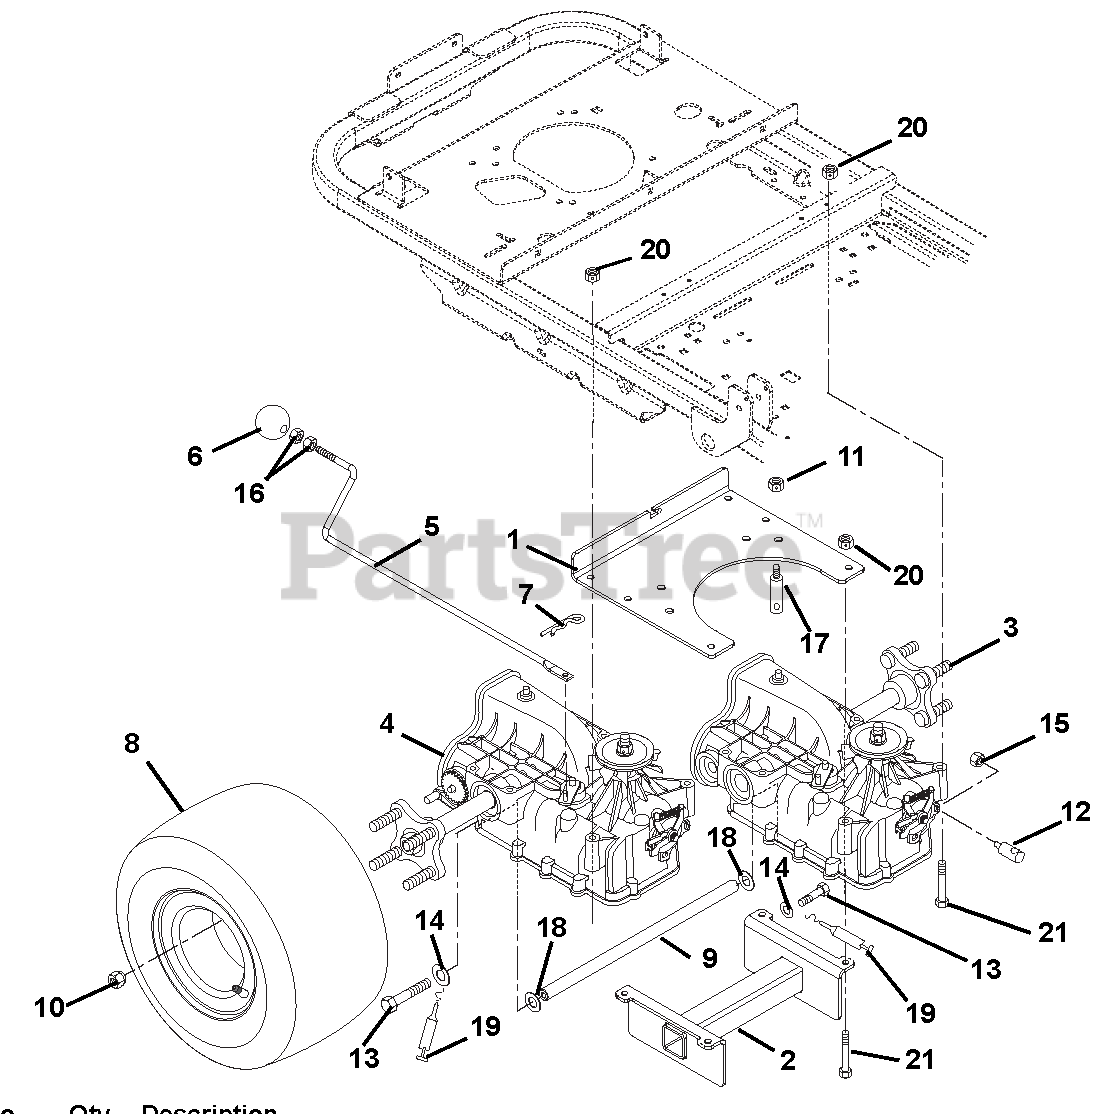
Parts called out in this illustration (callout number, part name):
1	BKT-TRANS AXLE SUPPORT
2	WLDMT-TRANS AXLE BRACE
3	IZT-LH (BIDIRECTIONAL RTN)
3	KIT, LH-BRAKE ARM IZT
4	IZT-RH (BIDIRECTIONAL RTN)
4	KIT,RH-BRAKE ARM IZT
5	ROD-DUMP IZT
6	KNOB, BALL 5/16-18 X 1.5
7	PIN-HAIR INT .08X.18X1.18 YWZC
8	ASSY-TIRE 9.5X18-2PLY
8	ASSY-TIRE 8.5X18 2PLY
9	ROD-AXLE BRACE
10	NUT-LUG .50-20 YWZC
11	@NUT-LK-NYL-FLG .38-16 YWZC
12	ROD PIVOT YWZC
13	@BLT-HEX .31-18X2.50 GR5 YWZC
14	@WSHR-LK .31X.078 REG YWZC
15	@NUT-LK-NYL-FLG .31-18 YWZC
16	NUT- JAM .312-18 YWZC
17	SHOULDER STUD
18	WSHR-FL-STL .328X.87X.179 YWZC
19	ADHSV SEALANT (BLUE) 250 ML
20	@NUT-LK-NYL-FLG .31-18 YWZC
21	@BLT-HEX .31-18X2.75 GR5 YWZC
